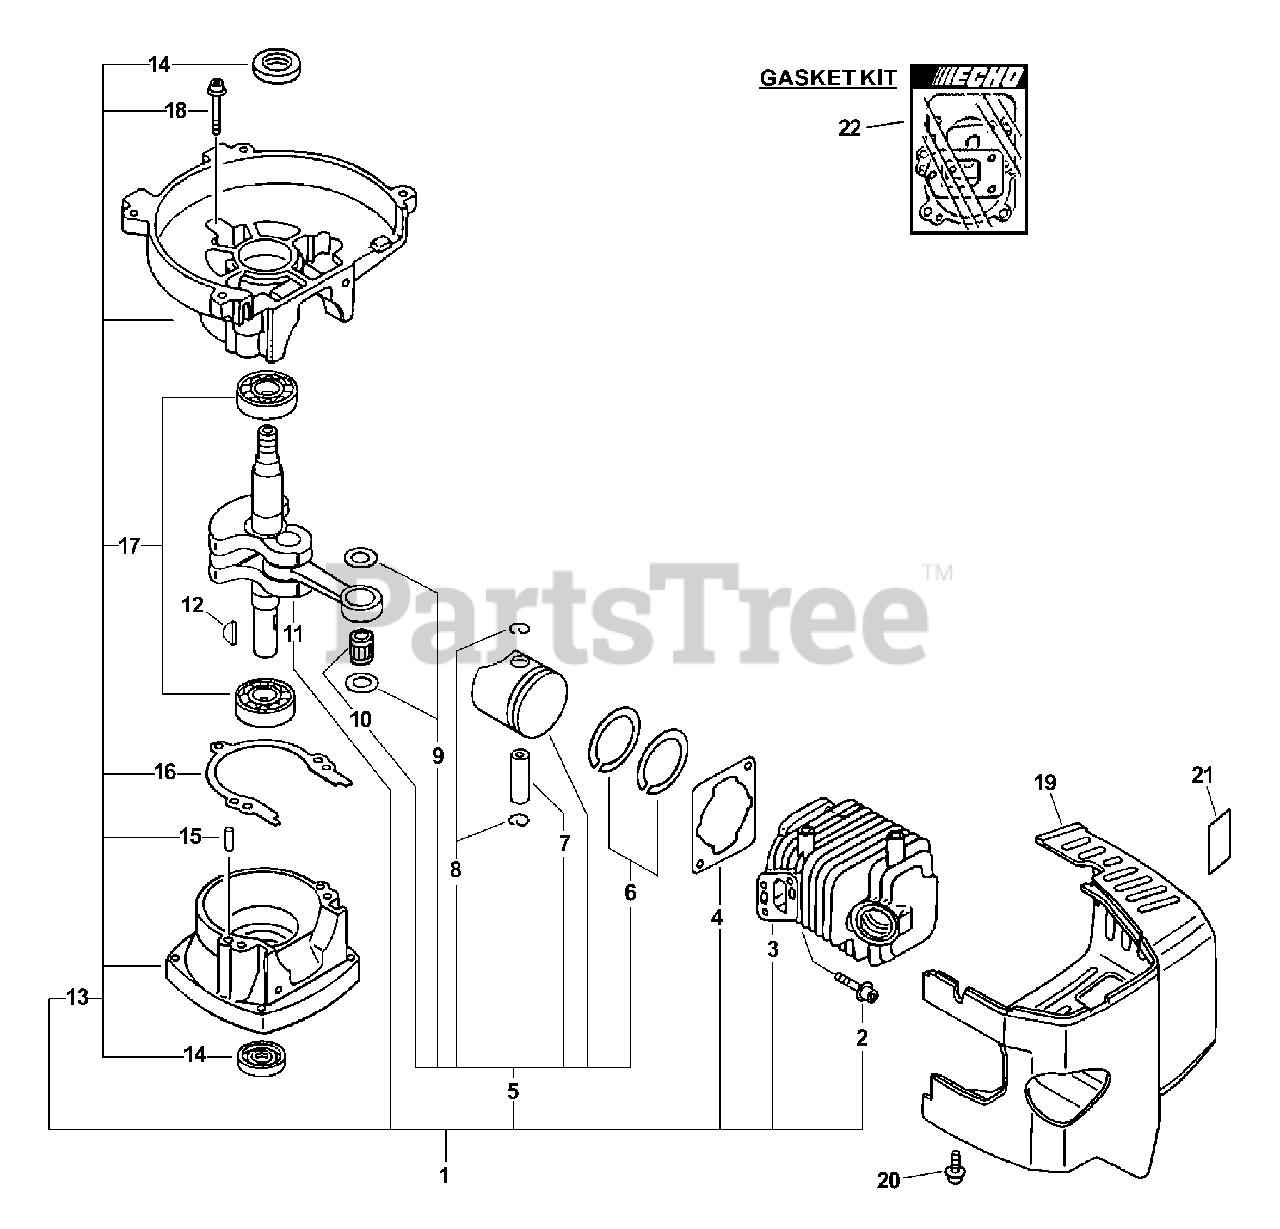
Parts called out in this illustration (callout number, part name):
1	SHORT BLOCK -- SB1021
2	SCREW - 5X22
3	CYLINDER
4	GASKET, CYLINDER
5	PISTON KIT
6	RING, PISTON
7	PIN, PISTON
8	RING, RETAINING
9	SPACER, PISTON
10	BEARING, NEEDLE
11	CRANKSHAFT ASSY
13	CRANKCASE KIT
14	SEAL, OIL
15	PIN - LOCATING
16	GASKET, CRANKCASE
17	BEARING, BALL - 6201
18	SCREW - 5X28
19	COVER, ENGINE - GRAY
20	SCREW - 4X18
21	LABEL - HOT SURFACE
22	GASKET KIT
